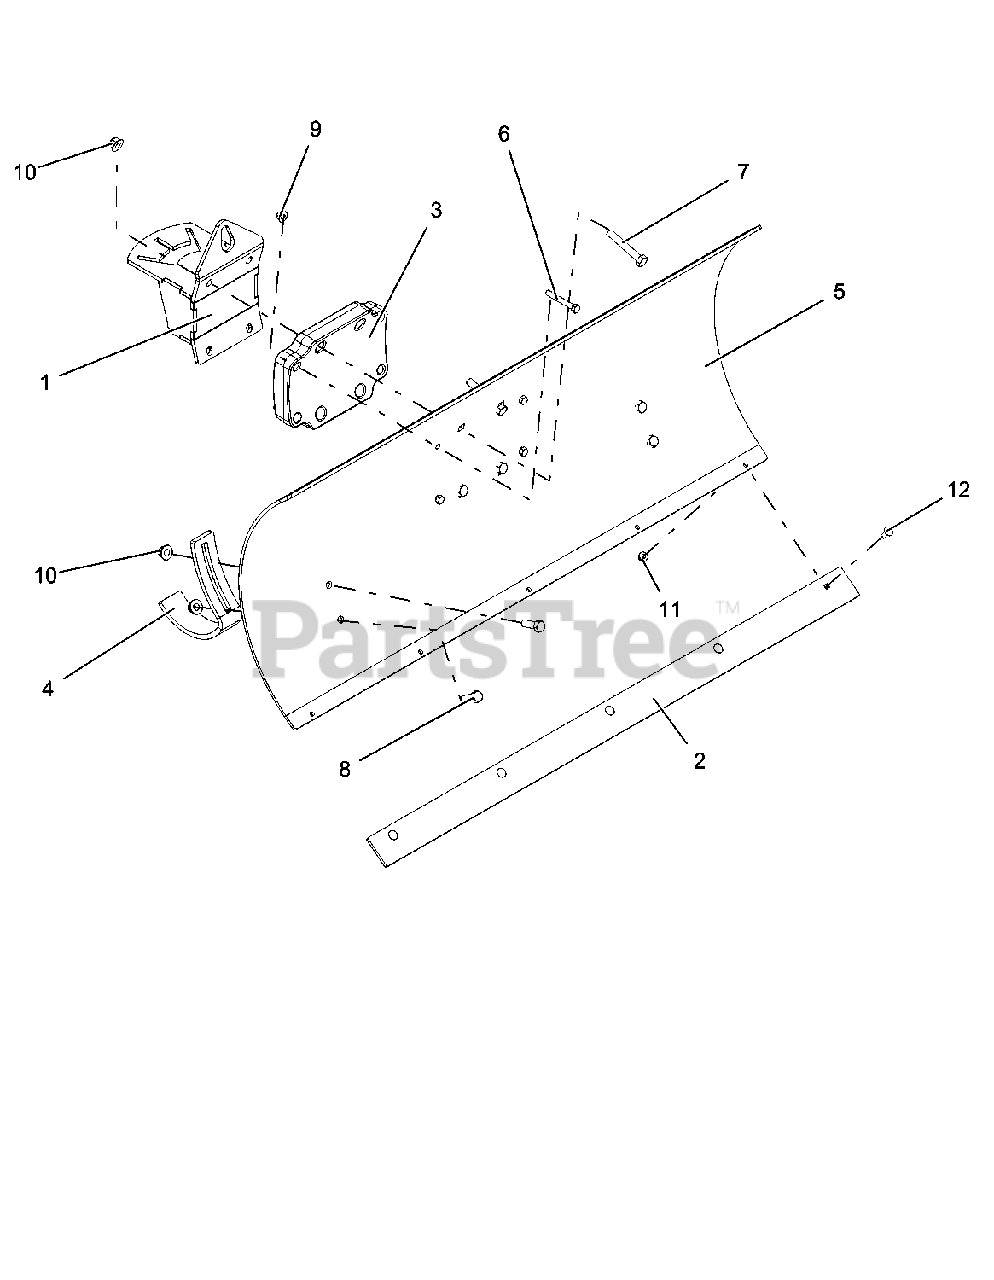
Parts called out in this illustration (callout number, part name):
1	WLDMT, BLADE MNT
2	SCRAPERBLADE, 2-WH'L SNOWDOZER
3	WT,BLADE
5	BLADE, DOZER 2-WHEEL
6	BLT, HEX .38-16X2.75 G5ZC120
7	BLT,HEX .50-13X3.25 G5ZC120
8	BLT,HEX .50-13X1.50 G5ZC120
9	NUT,LK-NYL-FLG .38-16 G5ZC120
10	NUT,LK-NYL-FLG .50-13 G5ZC120
11	NUT,LK-NYL-FLG .31-18 G5ZC120
12	BLT,RHSN .31-18X1.00 G5 ZC120
